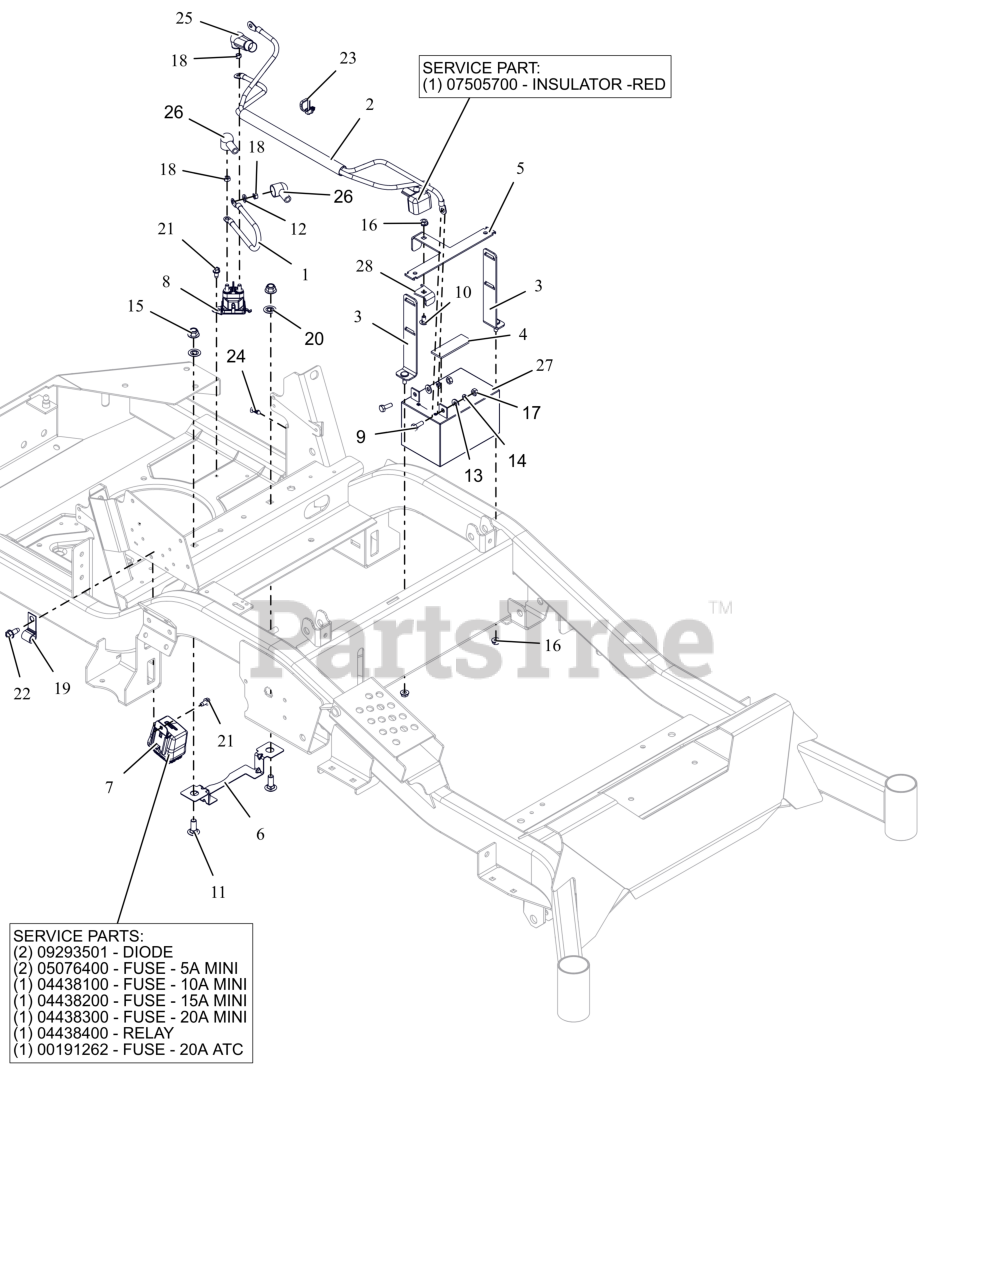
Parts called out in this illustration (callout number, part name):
1	CABLE, POS W/(2)1/4 RING 9.0LG
2	HARNESS, BATTERY HD
2	INSULATOR
3	WMT-BATT MNT HOLD DOWN FORMED
4	PAD,RBR 1.0"X3.0" W/ADHESIVE
5	BRKT- BATTERY HOLD DOWN
6	GUARD, ELECTRICAL HARNESS
7	HARNESS, WIRE
7	DIODE, CONNECTOR SHELL
7	FUSE, 5 AMP MINI-ATC
7	FUSE,10 AMP MINI-ATC
7	Fuse, 15 AMP MINI-ATC
7	FUSE,20 AMP MINI ATC
7	RELAY,MICRO5 TERML W/RESISTOR
7	FUSE, 20 AMP BLADE S/O
8	SOLENOID, STARTER (SEALED)
9	BLT, HEX .25-20X.75 G5 ZCC
10	BLT, RHSN .25-20X.500 G5 ZCC
11	BLT, RHSN .38-16X1.00 G5 ZCC
12	WSHR,LK-REG .312X.078 ZCC
13	WSHR,FLT .281X.625X.065 ZCC
14	WSHR,LK-REG .250X.062 ZCC
15	NUT,NYL-FLG .38-16 GF ZCC
16	NUT-LK-TOP-FLG .250-20 GF ZCC
17	NUT-STD .250-20 G2 ZCC
18	NUT-STD M6-1.0 ZCC
19	J-CLAMP
20	WSHR, RETAINING .35X.88X.03 NYL
21	SCR-TAP .25-20X.50 HWH ZCC
22	SCR,TAP .312-18X.75 HWH TR ZCC
23	CABLE TIE W/ TREE (.25 HOLE)
24	RIVET, .25 NYLON PANEL
25	BOOT, .65ID POS
26	BOOT, EYELET TERMINAL
27	BATTERY, 12V 12AH -190CCA
28	BRKT, BATTERY HOLD
